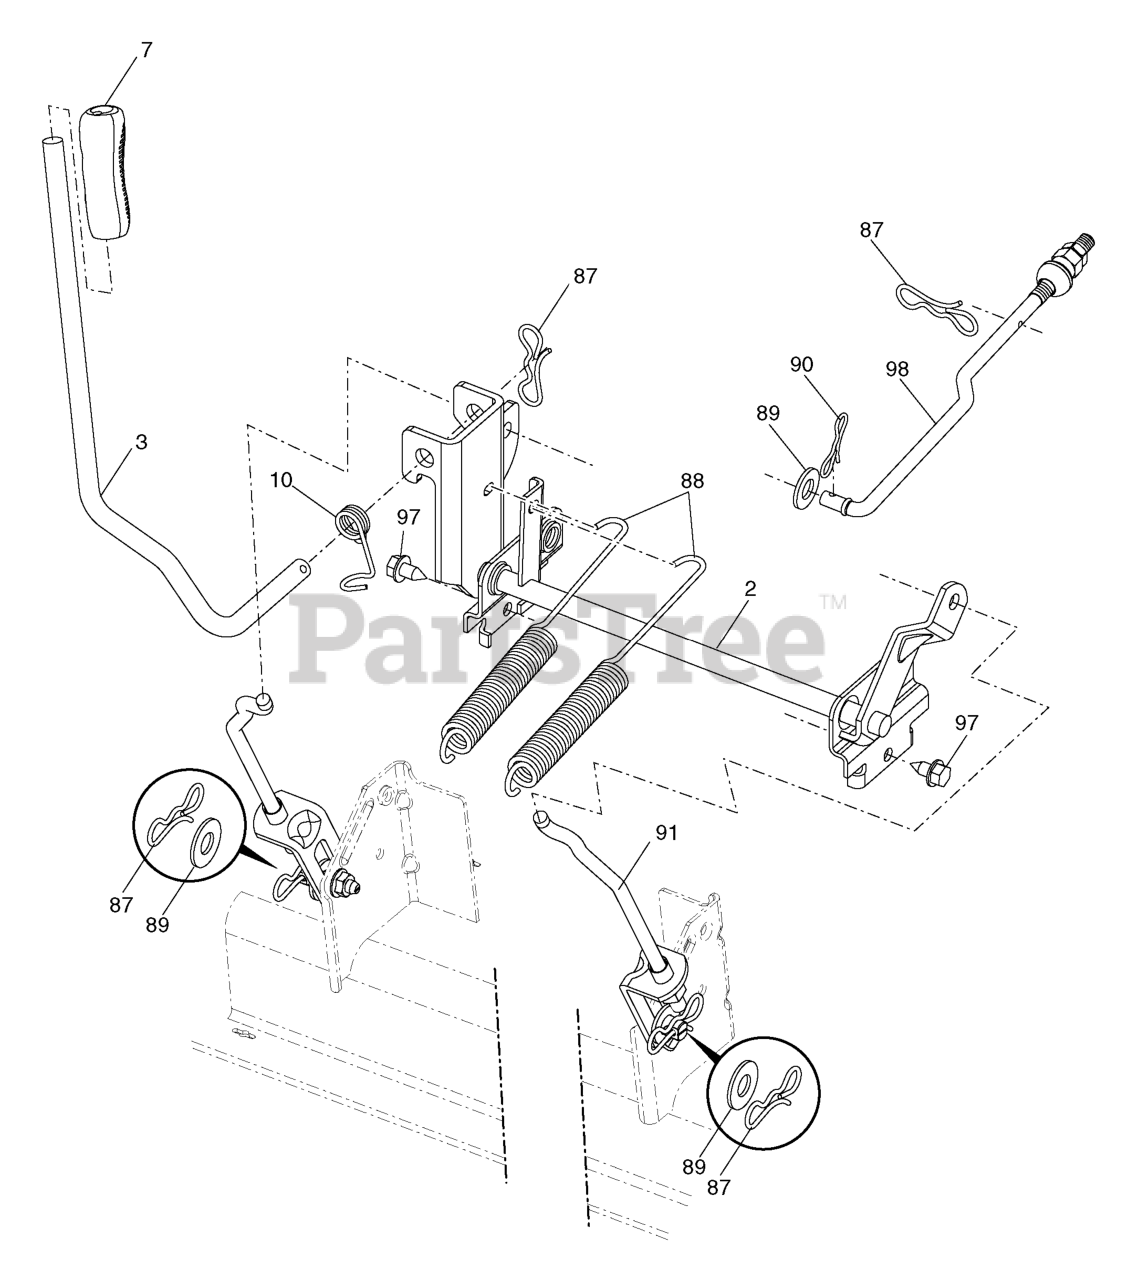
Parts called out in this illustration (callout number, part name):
2	SHAFT.ASM.LIFT.CROSS.H
3	LEVER.LIFT.HANDLE.GT
7	GRIP.LEVER.5625.ID
10	SPRING.TORSION.LIFT.HANDLE
87	PIN.COTTER.7/16.BOW TI.
88	SPRING.LIFT.ASSIST.GT2
89	WASHER.CLEAR.ZINC
90	PIN.COTTER.5/16.BOW TI
91	LINK.ASM.LIFT.REAR
97	SCREW 3/8-16X3/4
98	LINK.ASM.SUSP.FRONT.MWR.10.5
